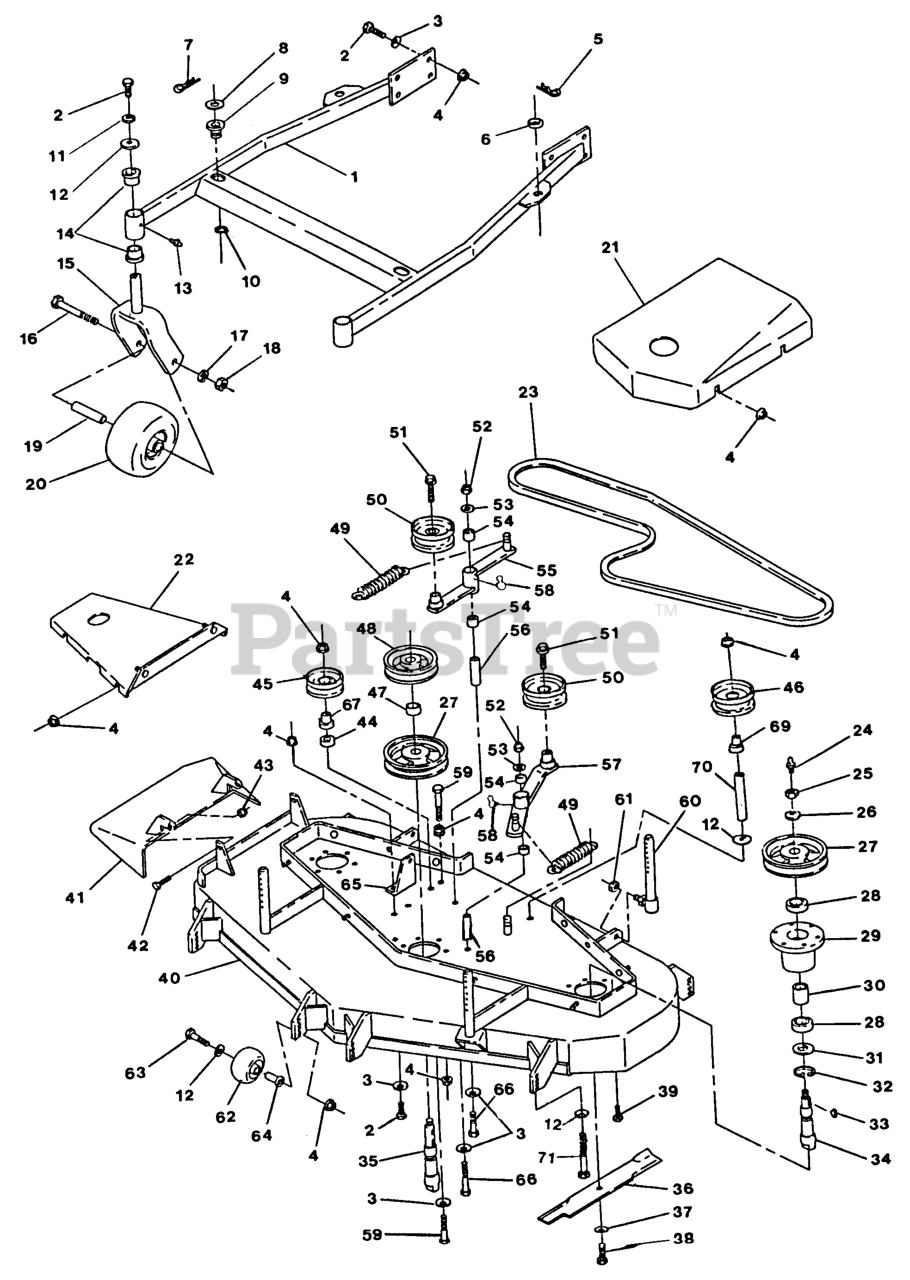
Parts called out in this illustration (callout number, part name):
5	PIN,HAIR COTTER
8	WASHER-FLAT
9	BUSHING-DECK
23	BELT,BLADE DRIVE
26	WASHER-SPRING
27	SHEAVE,BLADE DRIVE
30	SPACER,BEARING
31	SEAL,MECHANICAL DUST
32	RING,SNAP WLDS N5000-244
34	SPINDLE-OUTER BLADE
35	SPINDLE-CENTER BLADE
37	WASHER-SPRING
39	SCRW,TPTTE HH
41	WLD,CHUTE DISCHARGE
46	PULLEY-IDLER
47	SPACER-TUBE
48	SHEAVE,MOWER DRIVE
49	SPRING-EXTENSION
50	IDLER,PULLEY
54	SLEEVE-BEARING
55	ASM,IDLER ARM
56	BUSHING-PIVOT, IDLER
57	ASM,IDLER ARM
61	SPINDLE-OUTER BLADE
62	ROLLER-SCALP, ANTI
63	SCRWCAPHH
64	BUSHING-ROLLER
65	BRACKET,SPRING ANCHOR
66	SCREW-HH
67	BUSHING-IDLER
68	NUT-WING
69	BUSHING,IDLER
70	SPACER-FENDER
